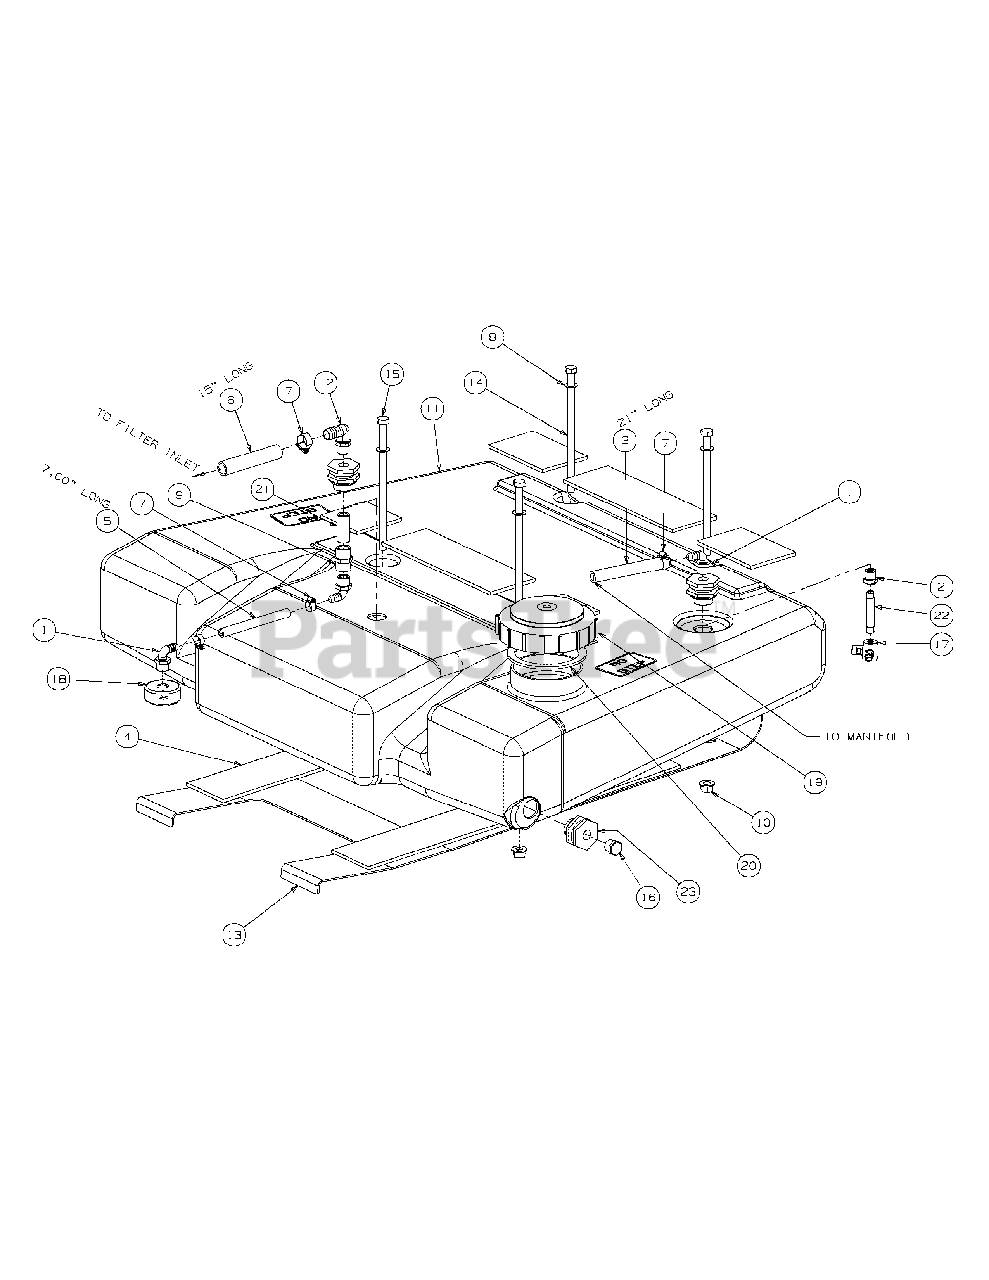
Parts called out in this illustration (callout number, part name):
1	Hose Barb, 1/2 NPT, 1/2 Nylon
2	Adapter, 1/4 NPT, 1/2 NPT
3	Hose, 1/2" sold by the ft.
4	Foam, Adhesive Backed, 4'' x 1/4'' by ft.
5	Hose, 3/8 by the ft.
6	Hose, 3/4 by the ft.
7	Hose Clamp, 1/2, 7/8
8	Flat Washer, .536 ID x .93 OD x .050
9	Coupling, 1/2" (F) NPT
10	Nut, 1/2-20
11	Tank, 40 Gallon
12	Elbow Fitting, 1/2 MNPT x 3/4
13	Tank Skid Plate
14	Hex Head Cap Screw, 1/2-20 x 9.00
15	Hex Head Cap Screw, 1/2-20 x 10.00
16	Pipe Plug, 1/2 NPT
17	Jet Agitator
18	Fitting, Tank
21	Nipple, 1/2"-14 x 2.00
22	Nipple, 1/4 NPT x 3"
23	Fitting, 1/2 Double Threaded
